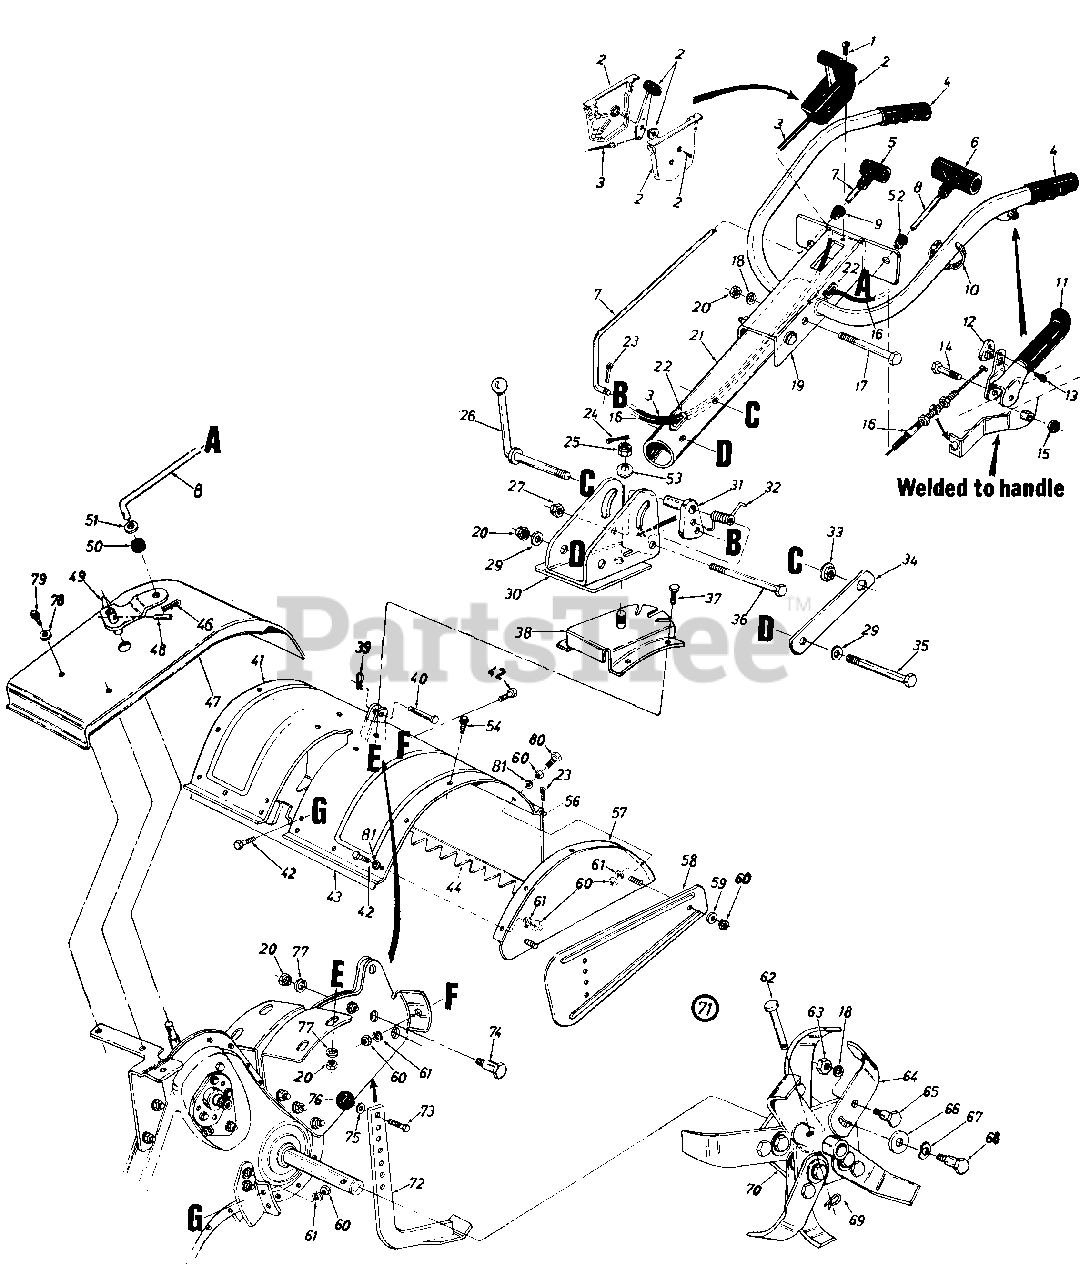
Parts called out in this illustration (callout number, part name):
1	Truss Mach. AB-Tap. Scr. #10 x .50" Lg.
2	Throttle Control Box Ass'y.
3	Throttle Control Wire
4	Handle Grip
5	Small "T" Knob
6	Large "T" Knob
7	Clutch Rod
8	Control Rod 37" Lg.
9	Snap On Bushing 3/8" Dia.
10	Cable Tie-Self Clinching
12	Barrel Cable Hold Down
13	Hex B-Tap Scr. #10 x .44" Lg.
14	Hex Bolt 3/8-24 x 2.25" Lg.
15	Hex Jam L-Nut 3/8-24 Thd.
16	Clutch Control Cable 53" Lg.
17	Hex Bolt 3/8-16 x 3.00" Lg.
18	L-Wash. 3/8" I.D.--H.D.
19	Handle Ass'y.
23	Cotter Pin 3/32" Dia. x .75"
24	Cotter Pin 3/32" Dia. x 1.25" Lg.
25	Hex Slotted Nut 5/8-18 Thd.
26	Handle Adj. Crank
27	Hex Cent. L-Nut 3/8-16 Thd.
29	Bell-Wash. .4" I.D. x .87" O.D.
30	Handle Pivot Bracket
31	Positioner Crank Ass'y.
32	Spring Handle Adj.
33	Hex Flange Nut 3/8-24 Thd.
34	Bracket Hex Nut Retainer
35	Hex Bolt 3/8-16 x 3.25" Lg.
36	Hex Bolt 3/8-16 x 3.00" Lg.--Gr. 8
37	Hex Bolt 3/8-16 x .75" Lg.
40	Clevis Pin .375" Dia.
43	Bracket Reinforcement--18"
46	Intern. Cotter Pin 5/16" Dia.
49	Shifting Crank Ass'y.
50	Rubber Washer .33" I.D.
51	Fl-Wash. .4" I.D. x 1.25" O.D.
52	Snap On Bushing 1/2" Dia.
53	Bell-Wash. .63" I.D. x 1.25"
54	Hex Wash. Tap Scr.
56	Tiller Flap Rod
60	Hex Nut 5/16-18 Thd.
61	L-Wash. 5/16" I.D.
62	Clevis Pin .375" Dia.
63	Hex Nut 3/8-24 Thd.
65	Shld. Bolt 1/2" Dia. x .175
66	Fl-Wash. .51" I.D. x 1 50"
67	Bell-Wash. .515" I.D. x 1.14"
68	Shld. Bolt 1/2" Dia. x .320
69	Intern. Cotter Pin
73	Hex Bolt 3/8-16 x .75" Lg.
74	Shld. Bolt 1/2" I.D. x .62" Lg.
75	Fl-Wash. 3/8" I.D. x 5/8" O.D.
76	Ball Knob
77	L-Wash. 3/8" I.D.
78	Fl-Wash. .281" I.D. x 62"
79	Hex Wash. Self-Tap Scr. 1/4-20 x 50" Lg.
80	Hex Bolt 5/16-18 x 1 1/4" Lg.
81	Fl-Wash. .344" I.D. x .62' 0.D.
